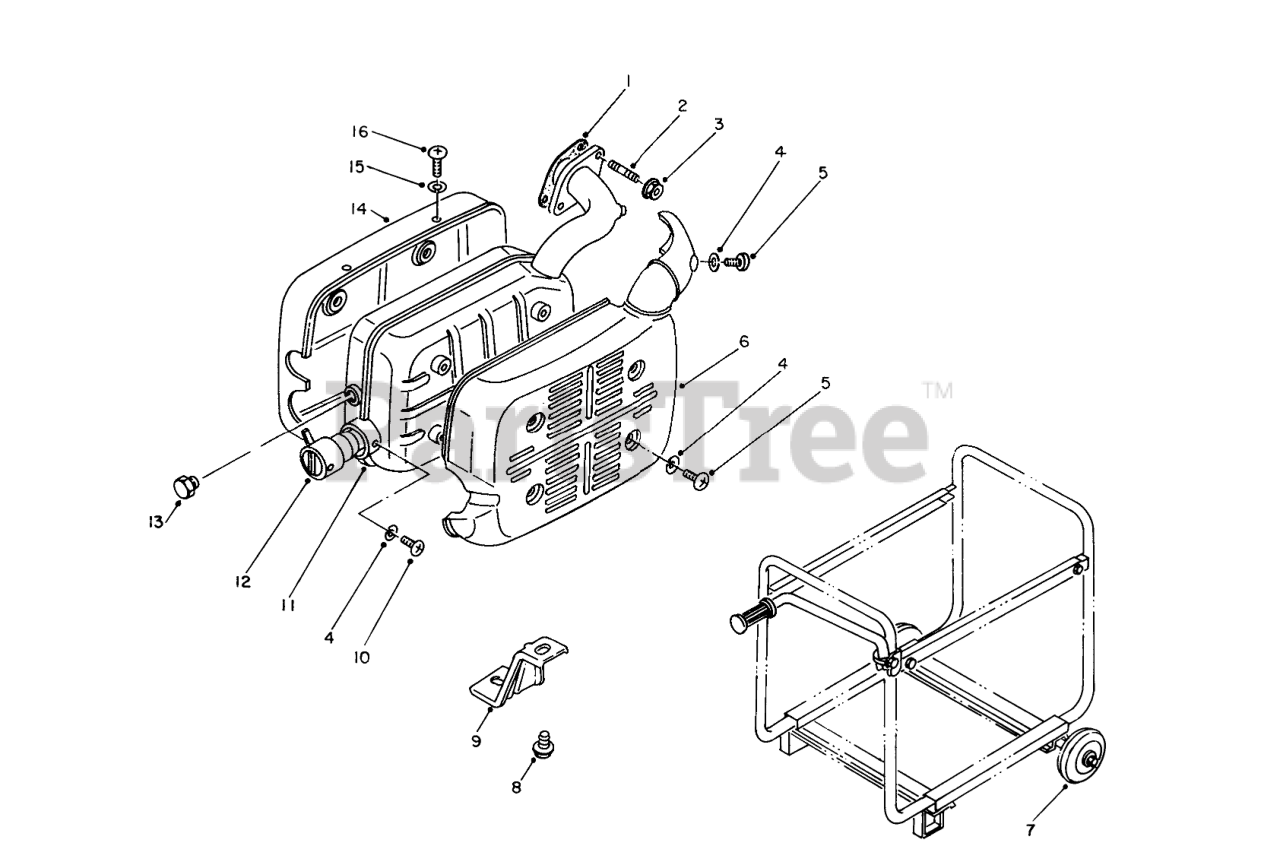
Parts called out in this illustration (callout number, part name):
1	EX GASKET
2	Stud Bolt
4	LOCKWASHER
5	SCREW
6	Cover-Front
7	Wheel Assembly (Optional)
9	Bracket Muffler
10	Screw
11	MUFFLER ASM
12	Cleanout Tube
13	Drain Plug
14	Cover-Rear
15	Lockwasher
16	Screw
